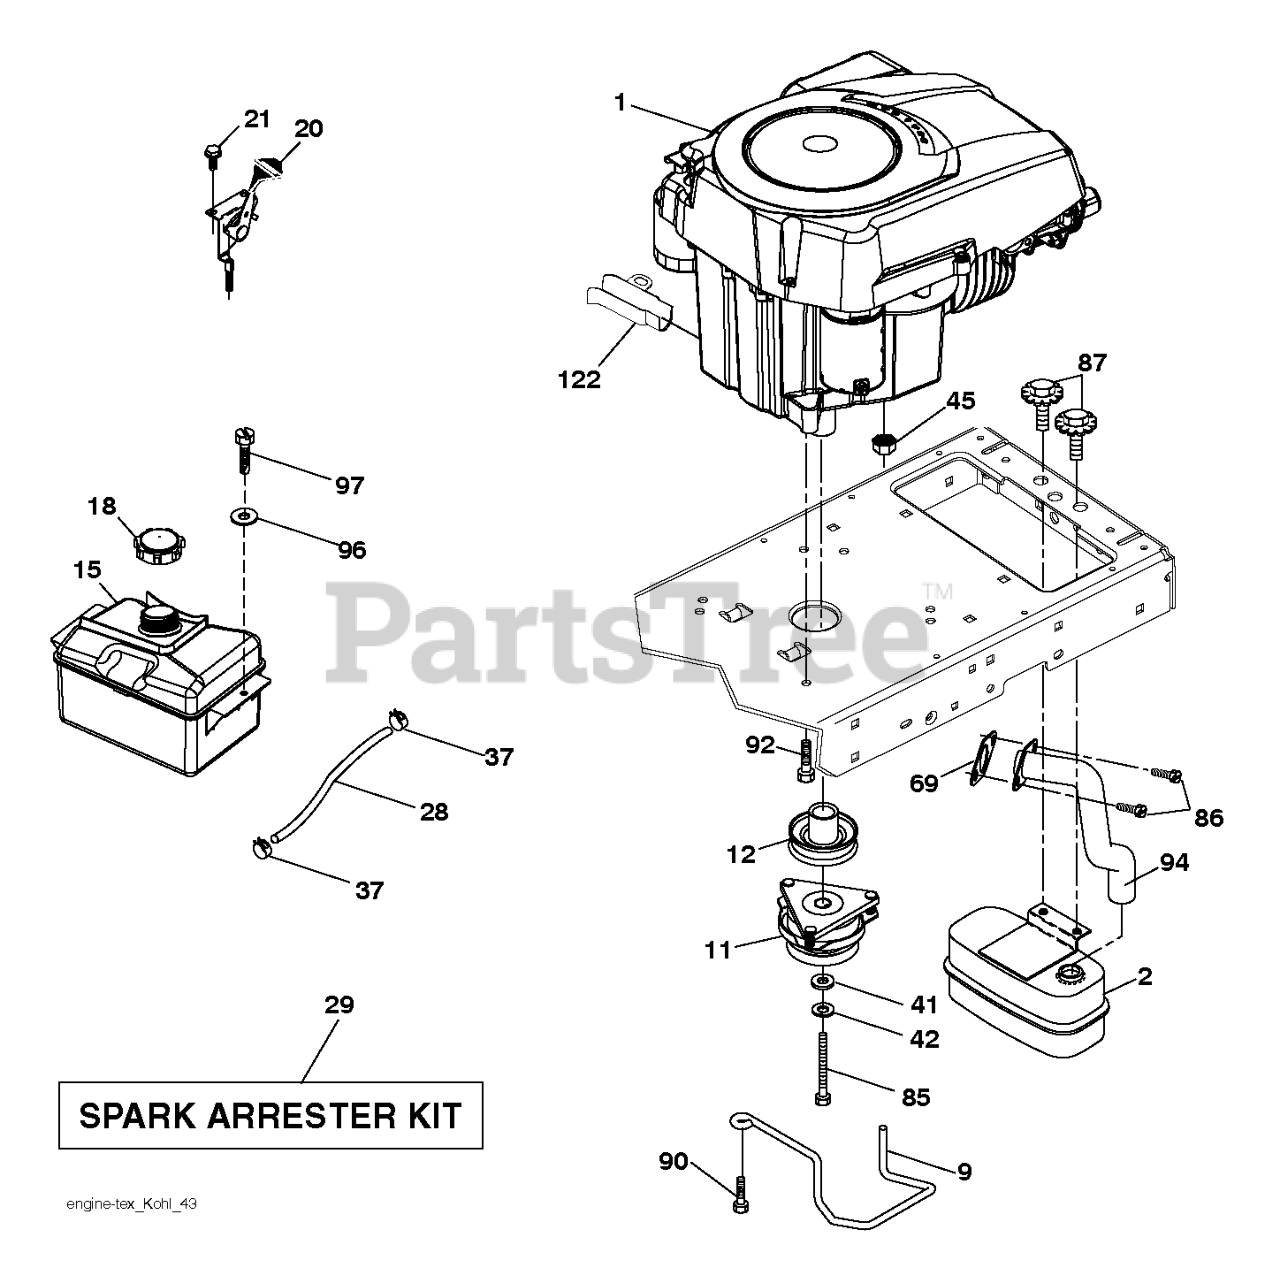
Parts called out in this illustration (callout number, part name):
2	MUFFLER.SINGLE.CYL.KOHL/B&S
9	KEEPER.BELT.ENGINE.4.2
11	CLUTCH.ELECTRIC.LT.48"*
12	PULLEY.ENGINE.TUFFTORQ
15	RP TANK FUEL FRT 1.5 GAL
18	CAP ASM.FUEL.2.25"FR.
20	CONTROL.TH/CK.C.
21	SCREW.#10 X 0.750.BOS
28	LINE.FUEL.20
29	KIT.SPARK ARRESTOR 794945 B&S
37	HOSE CLAMP
42	LOCKWASHER
45	NUT
69	GASKET.EXHAUST.KOHLER
85	BOLT HEX 7/16-20X4-1/4"
86	SCREW.SOCKET HD.5/16-1
87	BOLT.5/16-18UNCX3/4 W/SEMS.BLK
90	SCREW 3/8-16X1
92	SCREW 3/8-16X1
94	RP.TUBE.EXHAUST.KOHL.COURAGE
96	WASHER
97	SCREW HEXWSHR 1/4-20X3/4
122	EXTENSION DRAIN OIL
